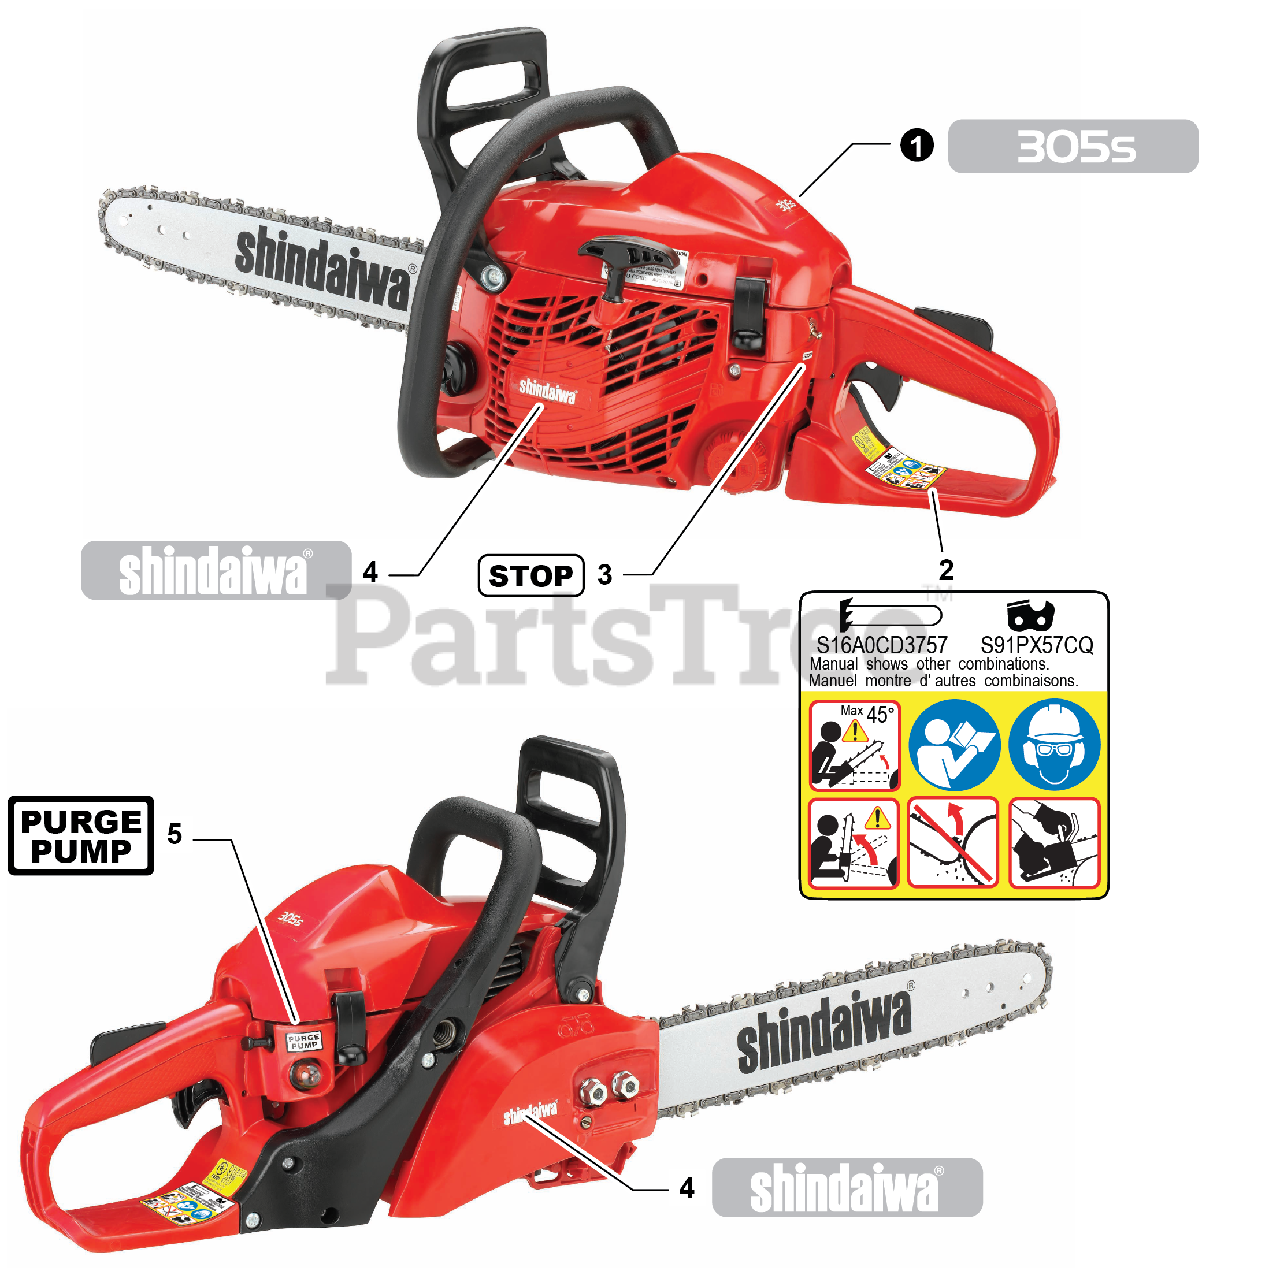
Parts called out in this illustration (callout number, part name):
1	LABEL, MODEL - 305S
2	LABEL, CAUTION
3	LABEL, STOP
4	LABEL - SHINDAIWA
5	LABEL, PURGE PUMP
